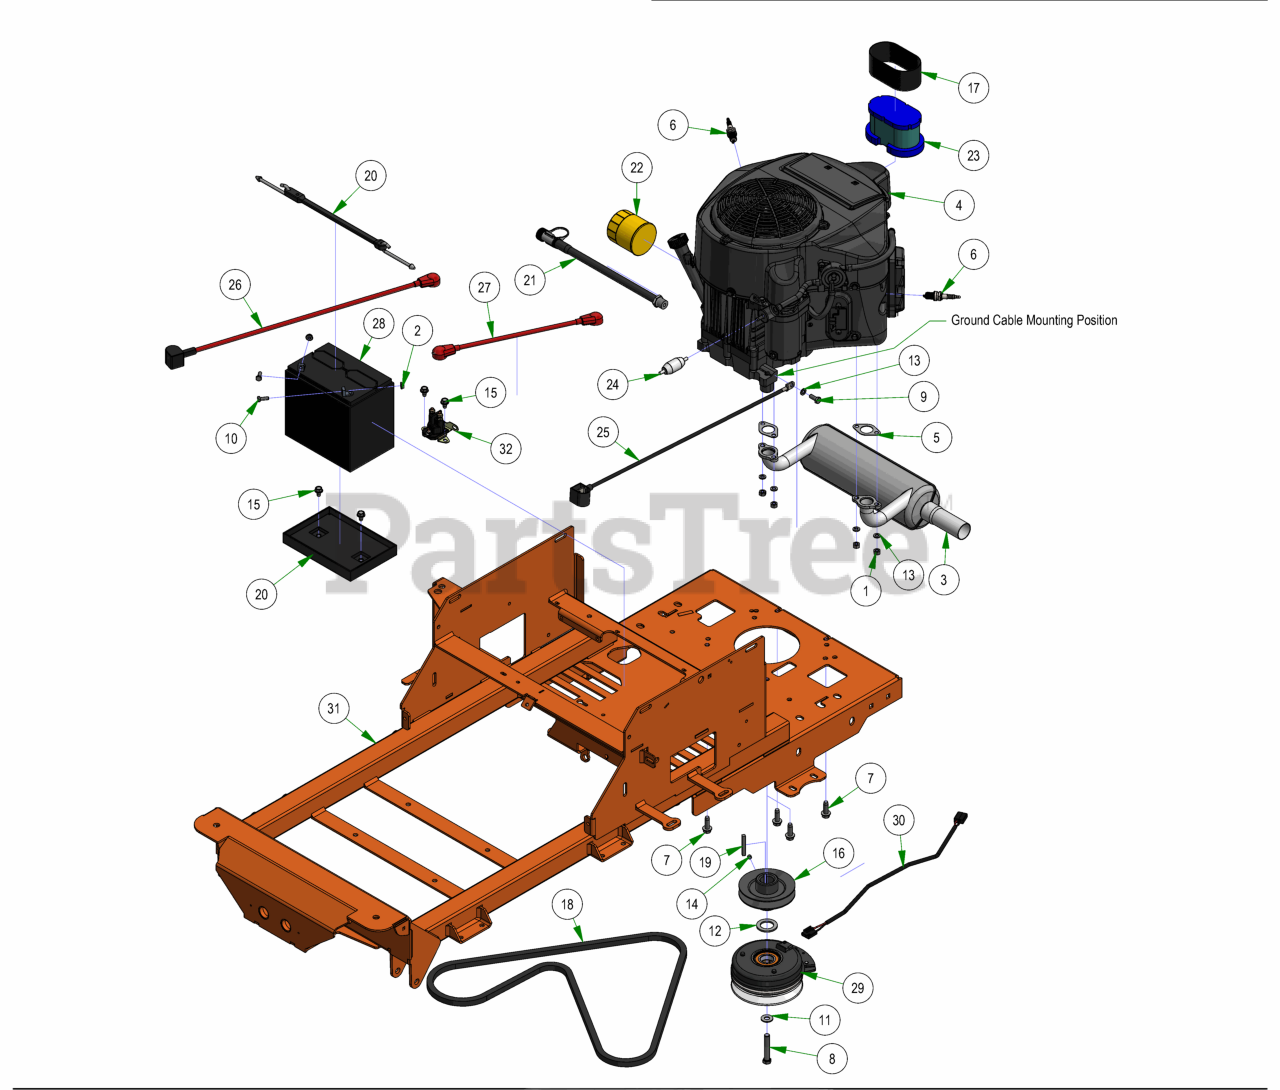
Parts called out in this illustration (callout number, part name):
1	M8-1.25 DIN 934 HEX NUT (CL.8) ZINC
2	1/4-20 HEX SERRATED FLANGE NUT HARD/ZINC
3	Kawasaki Muffler 1251
4	FR 730V-S16 Kawasaki Engine 1.125" shaft-ZT
5	Exhaust Gasket
6	Spark Plug - Kawasaki
7	3/8-16 X 1-1/8 HEX WASHER UNSLOT SERRATED (TRI-LOB) TRS ZINC YELLOW
8	7/16-20 X 2.5" HEX Bolt GR.8 W/Patch
9	M8-1.25 X 20MM DIN 933 HEX TAP BOLT (CL 8.8) ZINC
10	1/4-20 X 3/4 HEX CAP SCREW (GR.5) ZINC
11	3/8 FLAT WASHER USS (1" OD) ZINC
12	1.140 ID X 1.750 OD X .132 THICK FLAT WASHER PLAIN
13	5/16 SPLIT LOCKWASHER ZINC
14	5/16-24 X 1/4 SOCKET SET SCREW (CUP PT) PLAIN
15	5/16-18 X 1/2 HWH unslot (F) tcs zinc
16	4 3/4 Motor Pulley
17	Air Filter Pre-Cleaner for KAW
19	1/4 X 2 SQ MACHINERY KEY 1018 STL PLAIN
20	2023 Battery Hold Down Assembly
21	Kawasaki Oil Drain
22	22-26 Kaw Oil Filter FR Engine
23	Kawasaki Air Filter
24	Universal Inline Fuel Filter
25	24 inch Black Cable – MZ/ZT
26	24" Red Battery Cable
27	14" Red Battery Cable
28	SP-35 Battery
29	120 Ft Lb. Clutch - 1 1/8" Shaft
30	Clutch Pigtail
31	2025 ZT Elite Frame
